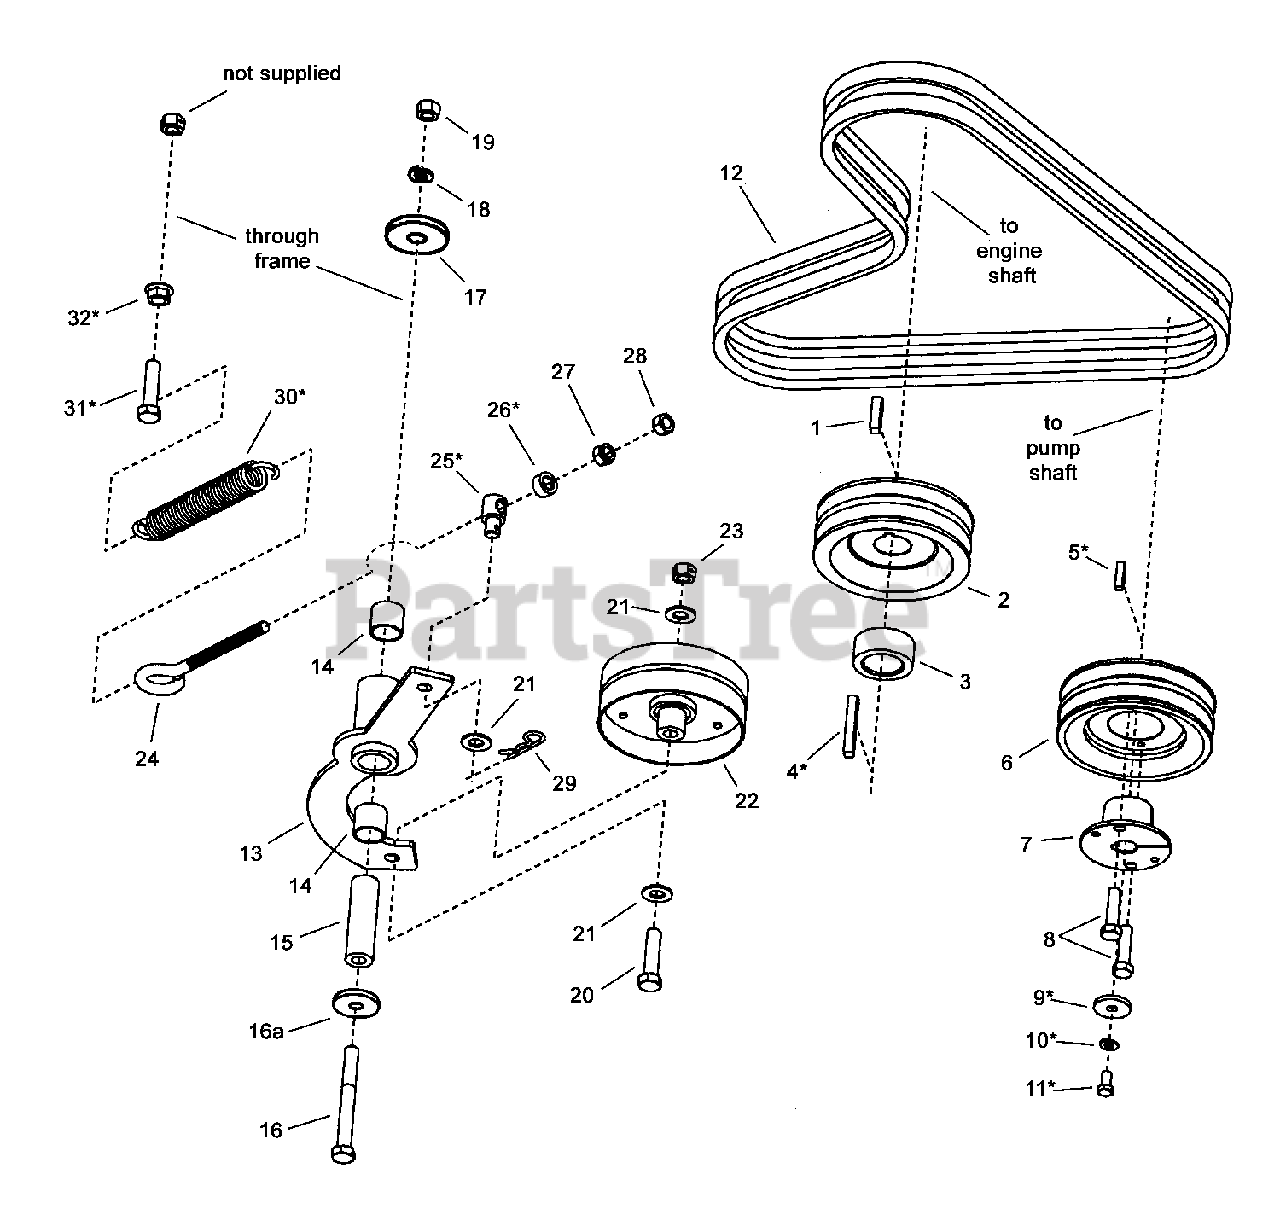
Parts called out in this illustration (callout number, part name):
1	KEY, Square 1/4
2	PULLEY, Double Engine
3	SPACER, Clutch
4	KEY, 1/4 Square x 2.25
5	KEY, 5mm x 20mm
6	PULLEY, Double Pump
7	BUSHING, Tapered X 15MM
8	SCREW, Hex Head Cap 5/16-18 X 1.25 GR 5 YZ
9	WASHER, Flange Lock .281 X 1.00 X .125 YZ
10	WASHER, Split Lock .263 X .375 X .062 YZ
11	SCREW, M6 1.0X12MM, Hex Head, CZ
12	BELT SET, Matched Traction Drive 47.5" EL
13	WELDMENT, Idler Arm
14	BUSHING, Sleeve 3/4 ID, GV3031224
15	PIVOT, Idler Arm GV3036304
16	BOLT, HHB, 3/8-16 X 3.50 YZ
17	WASHER, Flange Lock .468 X 1.85 X .25 YZ
18	WASHER, Split Lock 3/8
19	NUT, Hex 3/8-16
20	SCREW, Hex Head Cap 3/8-16 X 2 1/4 - YZ
21	WASHER, SAE 3/8
22	IDLER, Backside 4" OD X .391 ID X 1.25
23	NUT, Hex Center Lock 3/8-16 YZ
24	EYEBOLT, 5/16
25	SWIVEL, Adjustable
26	SPACER, .340I.D. X .63O.D. X .310THK
27	NUT, Hex 5/16-18 YZ
28	NUT, Hex Lock 5/16-18-3B YZ ESNA
29	PIN, Hair 3/32 X 1.5 YZ
30	SPRING, Extension 5.43" x .840" DIA
31	SCREW, Hex Head Cap 3/8-16 X 1-1/2 GR5 YZ
32	NUT, Hex Flange Lock 3/8-16 YZ
